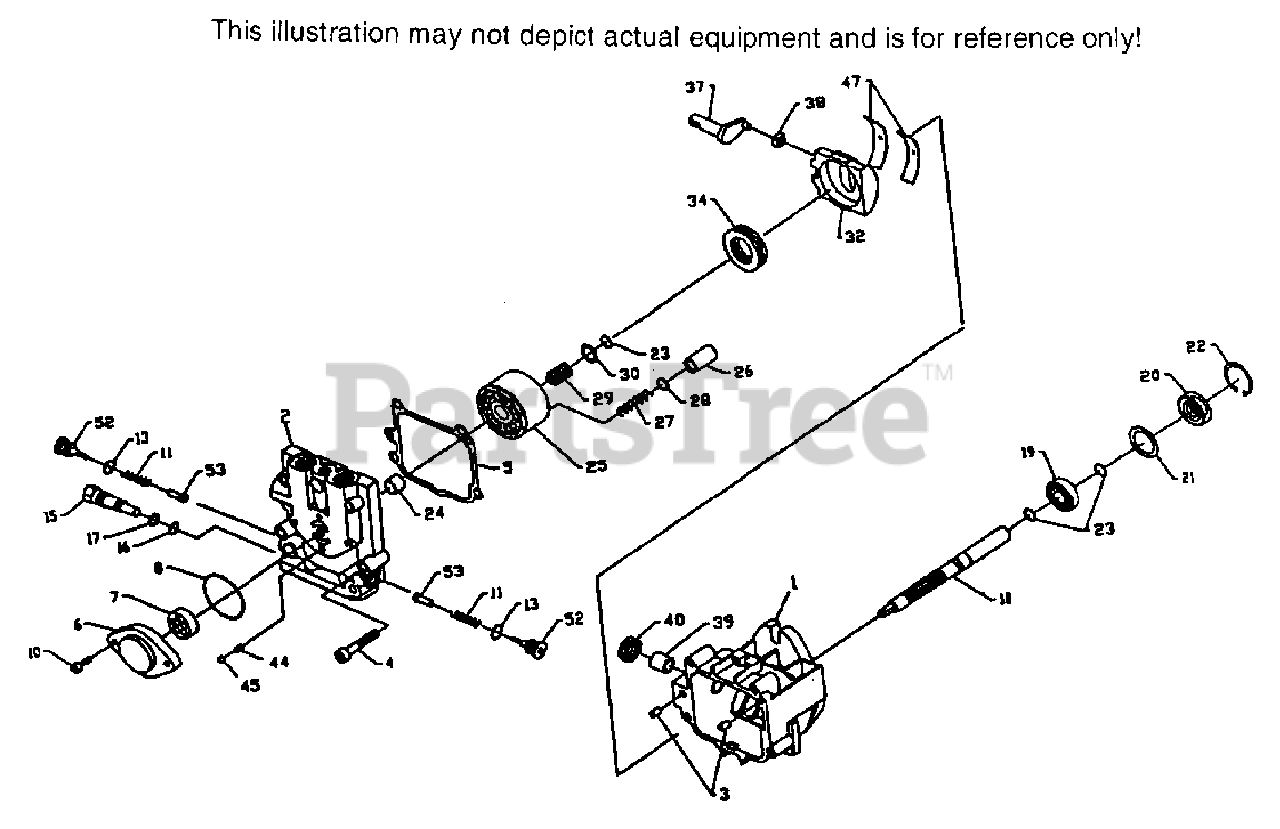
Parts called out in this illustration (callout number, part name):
1	HOUSING
2	END CAP
3	PIN, ST. HDLS.
4	SCREW, SOCKET HD.
5	END CAP GASKET
6	CHARGE PUMP ASSY.
7	GENERATOR ASSY.
8	"O" RING
10	SCREW, SOCKET HD.
11	SPRING
15	BYPASS VALVE
17	BACK-UP RING
18	PUMP SHAFT
19	BALL BEARING
20	LIP SEAL
21	SPACER
22	RETAINING RING
23	RETAINING RING
24	JOURNAL BEARING
25	CYLINDER BLOCK
26	PISTON
27	PISTON SPRING
28	PISTON WASHER
29	BLOCK SPRING
30	BLOCK THRUST WASHER
32	SWASHPLATE
34	ROLLER THRUST BEARING
37	TRUNNION ARM
38	SLOT GUIDE
39	JOURNAL BEARING
40	LIP SEAL
44	CHECK RELIEF SPRING
47	CRADLE BEARING
52	CHECK PLUG
53	CHECK VALVE ORIFICE
